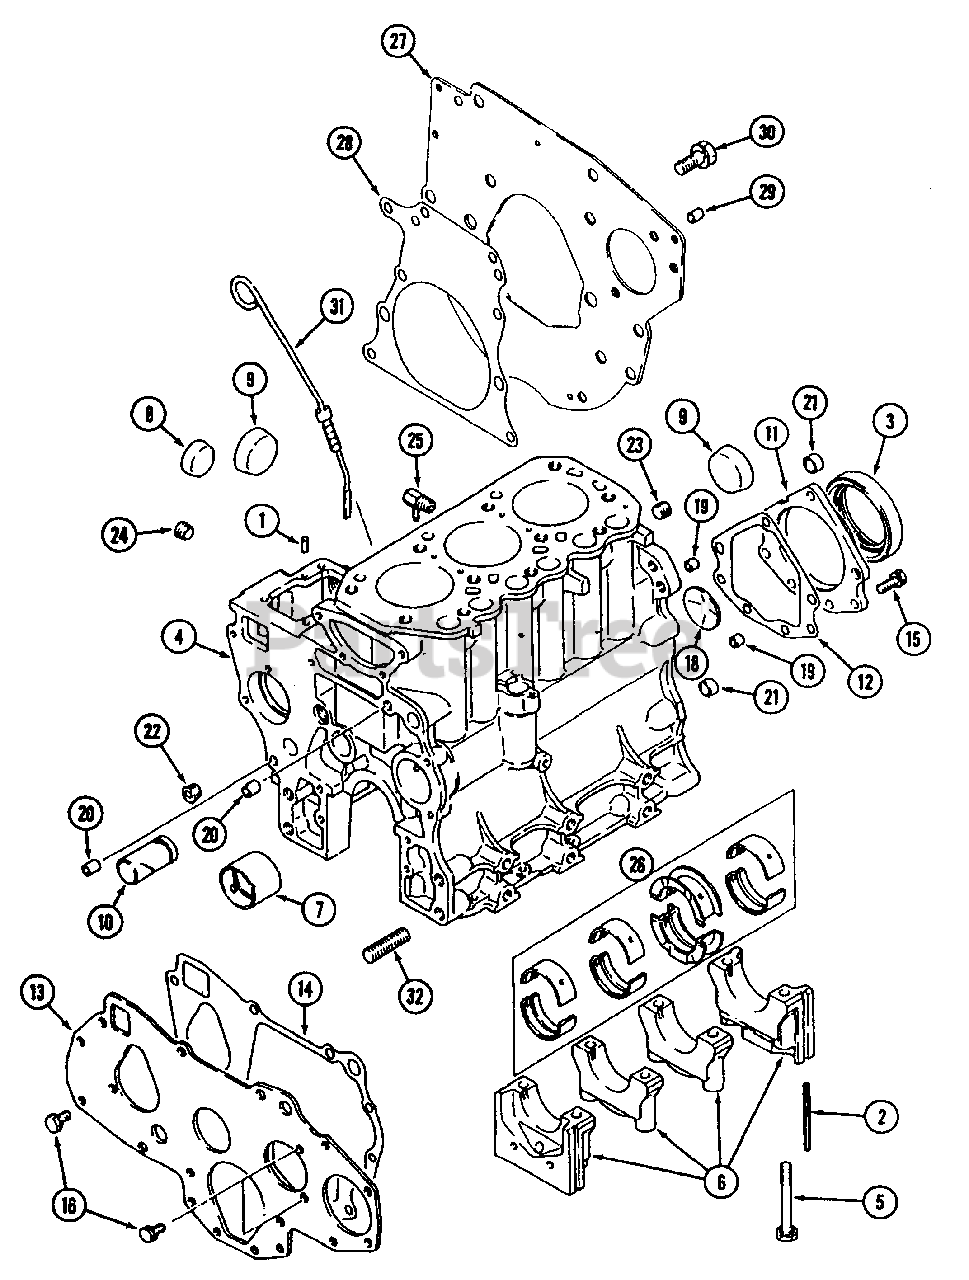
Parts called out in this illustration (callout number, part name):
4	Block Sub Ass'y., Cylinder
5	Bolt, Bearing Cap
6	Cap Ass'y., Bearing
7	Bush, Camshaft
8	Plug, Expansion
9	Cap, Sealing
10	Shaft, Idler
11	Case, Oil Seal
12	Gasket, Oil Seal
13	Plate, Front
14	Gasket, Front Plate
15	Bolt, W/Washer
16	Bolt, W/Washer
18	Plug, Expansion
19	Bushing, Knock
20	Bushing, Knock
21	Bushing, Knock
22	Plug, Taper
23	Plug, Taper
24	Plug, Taper
25	Joint, Water Drain
26	Bearing Set, Crankshaft STD
27	Plate, Rear
28	Gasket, Rear Plate
30	Bolt, W/Washer
31	Gauge, Oil Level
